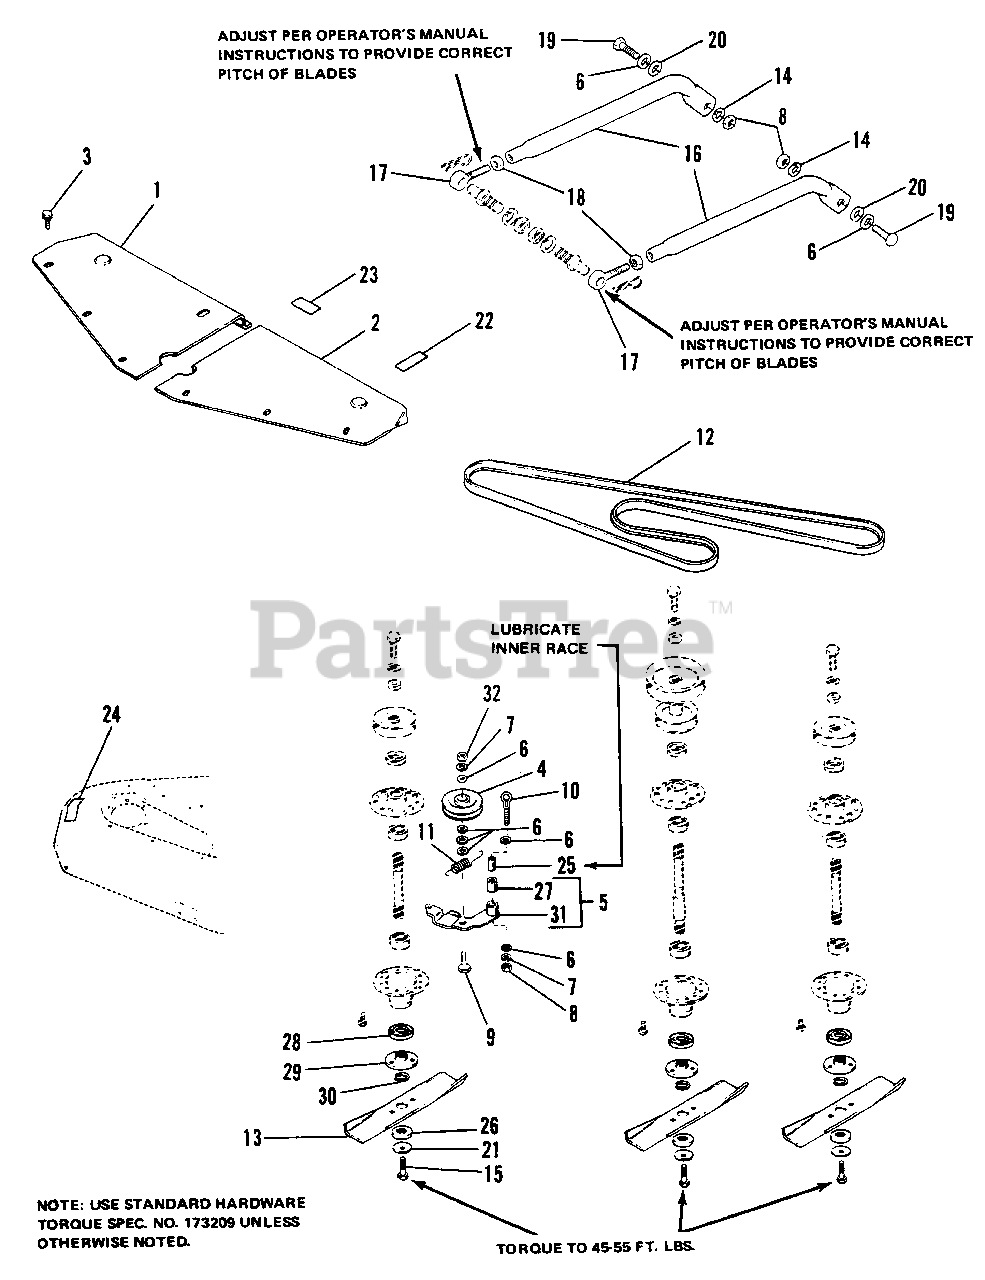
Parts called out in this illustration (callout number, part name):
1	COVER, R.H.
2	COVER, L.H.
3	SCREW, Hex, Taptite, 1/4-20 x 3/8
4	PULLEY, Idler
5	LEVER ASSY, Idler (w/Bushings)
6	WASHER, Plain, 5/16
7	LOCKWASHER, 3/8
8	NUT, Hex, Full, 3/8-16
9	CAPSCREW, Hex Hd., 3/8-16 x 1-1/4
12	BELT, V, Arbor Drive
13	BLADE, 42" Mower
14	LOCKWASHER, 1/2
15	CAPSCREW, Hex Hd., 7/16-14 x 1
16	ARM, Adjusting
18	NUT, Hex, Jam, 1/2-20
19	CAPSCREW, Hex Hd., 3/8-16 x 1
21	WASHER, Spring
22	DECAL, Danger
23	DECAL, Belt Installation
24	DECAL, Danger
25	RACE, Inner
26	WASHER, Spline
28	SHIELD, Grass
29	ADAPTOR, Blade
30	RING, Self Locking
31	LEVER ASSY, Idler
32	NUT, Hex, Jam, 3/8-16
